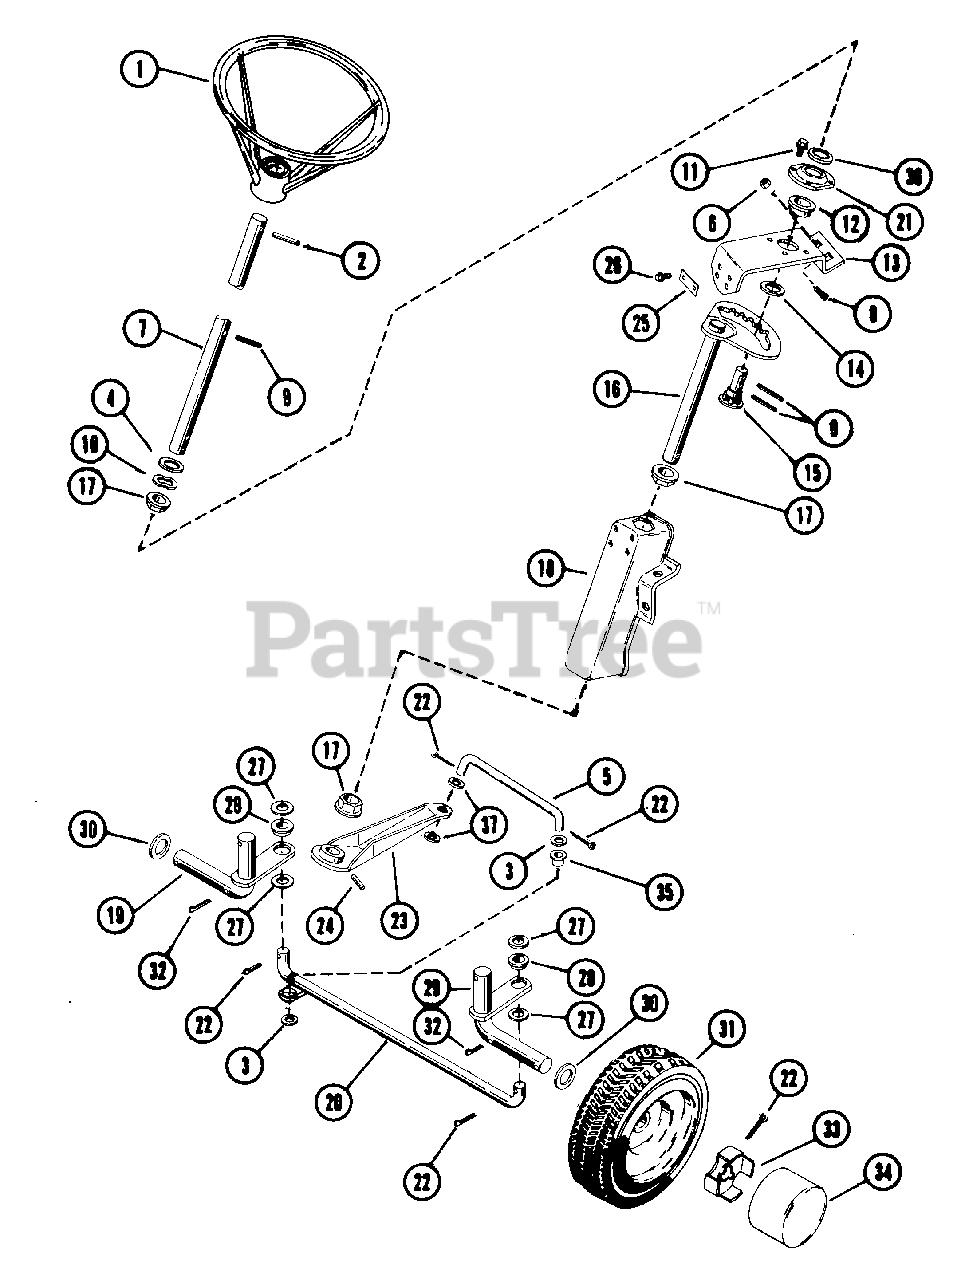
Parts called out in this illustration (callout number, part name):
1	STEERING WHEEL
2	PIN-ROLL .250X1.75
3	WSHR-FL-STL .382X.812X.023 PL
4	WSHR-FL-STL .755X1.375X.062 PL
5	STEERING LINK
6	NUT-LK .312-18 GR A PL
7	STEERING SHAFT
8	BLT-RDHDSQSHNK .31-18X.50 YZ
9	PIN-ROLL .188X1.00
10	SPRING WASHER
11	SCR-TAP 10-24X.25 CRSLPH PL 1A
12	BSHG-FLG .625X1.156X.375 SI
13	STEERING SUPPORT
14	WSHR-FL-STL .630X1.005X.062 PL
15	STEERING PINION
16	STEERING GEAR
17	FLANGE BUSHING
18	DEEP DRAW STEERING BOXES
19	R H WHEEL SPINDLE
20	TIE ROD
21	RETAINING PLATE
22	PIN-COTR .12X1.0 PL
23	STEERING ARM
24	PIN-GRV .188X1.25 TP A
26	BLT-SERHFWH .31-18X.75 PL
27	WSHR-FL-STL .505X.875X.024 PL
28	BSHG-FLG.500X.625X.312X.750NY
29	L H WHEEL SPINDLE
30	SPINDLE WASHER
31	FRONT WHEEL ASSEMBLY
31	TIRE 4.10/3.50-4
31	WHL
31	ZERK FITTING
31	BSHG-FLG .750X1.380X.750X1.557
32	PIN-COTR .12 X 1.25 PL
33	SPINDLE CUP
34	HUB CAP
35	BSHG-FLG .372X.500X.312X.625NY
36	PUSH NUT, .50
37	WSHR-FL-STL .406X.865X.094 PL
